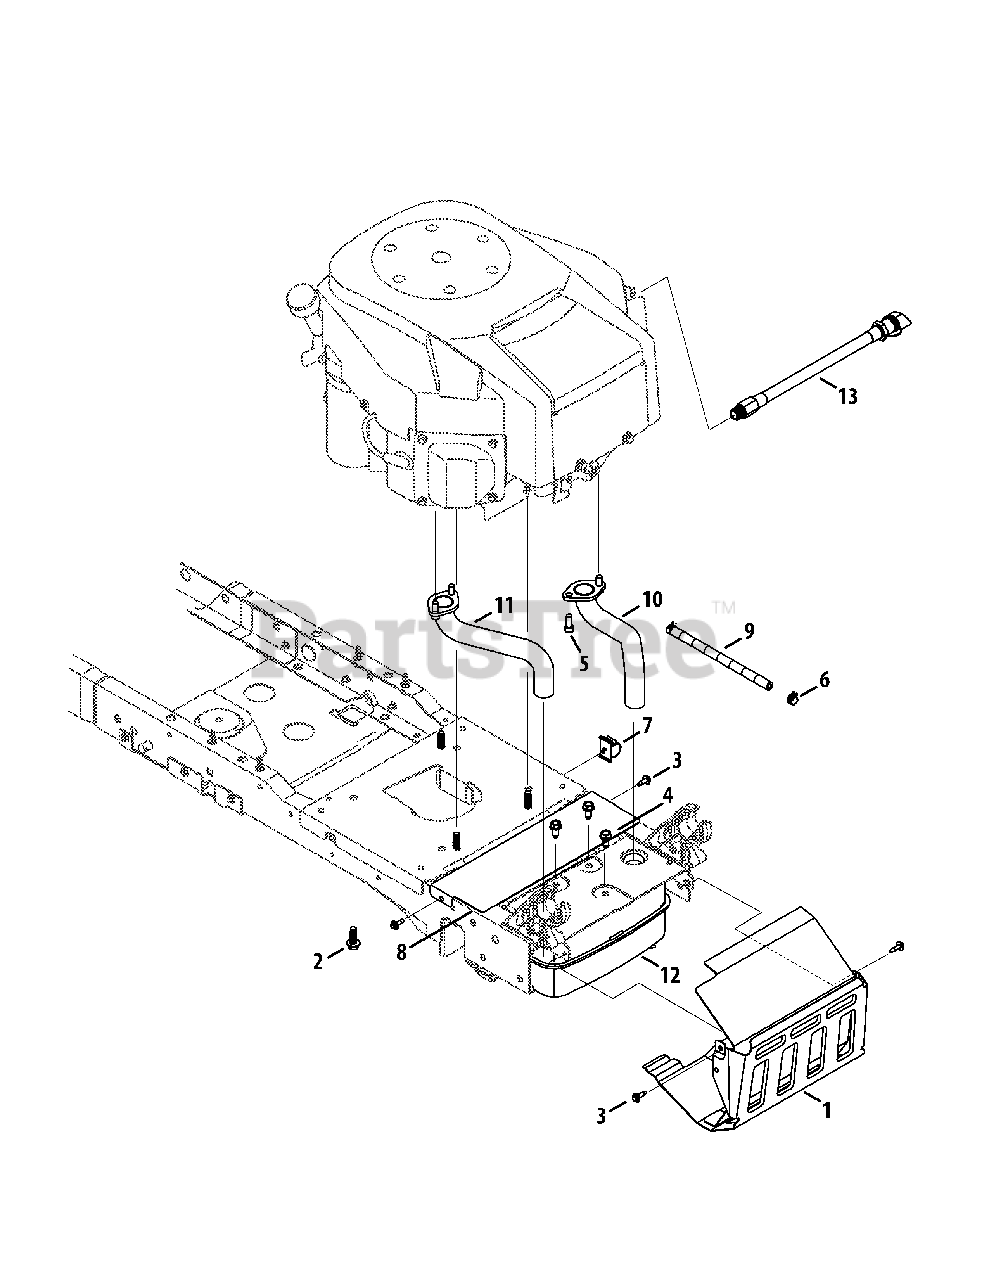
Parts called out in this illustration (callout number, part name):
1	Shield Ass’y, Muffler
2	Screw, Self-tapping, 3/8-16, 1.0
3	Screw, M6-1 x .625
4	Screw, Self-tapping, M8-1.25, .750
5	Screw, Sokt Head, 5/16-18, .750
6	Clamp, Hose, .490 Dia.
7	Push Mount Wire Clip, .750
8	Muffler Shield
9	Hose, Fuel, Low Permeation, 1/4
10	Exhaust Pipe, LH
11	Exhaust Pipe, RH
12	Muffler, Kohler
13	Drain, Oil
